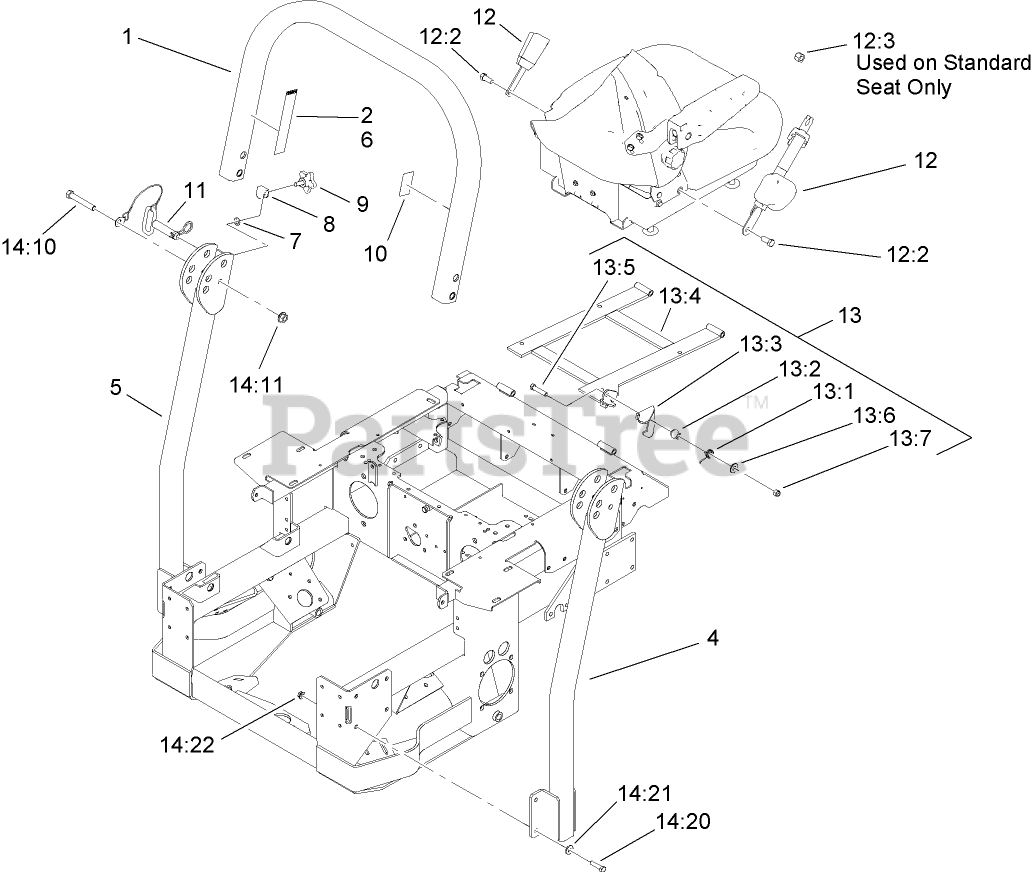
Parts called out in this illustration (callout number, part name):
1	Upper Tube ASM
2	DECAL-WARNING, FOLDING ROPS
4	TUBE-SUPPORT, RH
5	TUBE-SUPPORT, LH
6	DECAL-WARNING
7	NUT-PUSH
10	DECAL-ROPS
11	PIN-FOLD, ROPS
12	RETRACTABLE SEATBELT KIT
12:2	SCREW-HH
12:3	NUT-LOCK
13	SEAT FRAME ASM
13:1	SPRING-TORSION, LATCH
13:2	BUSHING-LATCH, SEAT
13:3	CATCH-LATCH, SINGLE
13:4	SEAT FRAME ASM
13:5	SCREW-HH
13:6	WASHER-FLAT
13:7	NUT-LOCK, NI
14	BAG-BOLT
14:10	SCREW-HH
14:11	NUT-HF
14:20	SCREW-HH
14:21	WASHER-BELLEVILLE
14:22	NUT-HHF, WHIZ
